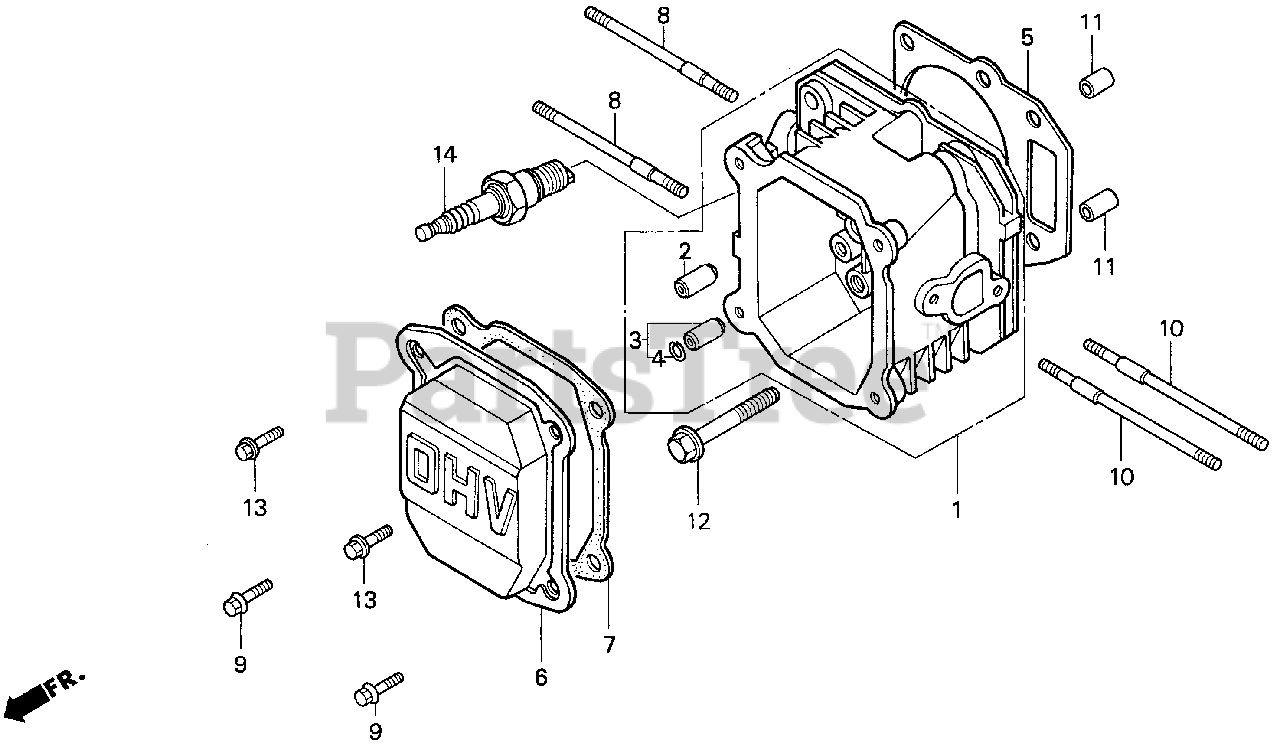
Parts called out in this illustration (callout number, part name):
1	CYLINDER HEAD
2	GUIDE, VALVE (OS)
3	GUIDE, EX. VALVE (OS)
4	CLIP, VALVE GUIDE
5	GASKET, CYLINDER HEAD
6	COVER, HEAD
7	GASKET, HEAD COVER
7	GASKET, CYLINDER HEAD COVER
8	BOLT, STUD (6X83)
9	BOLT, FLANGE (6X13)
10	BOLT, STUD (6X97)
11	PIN, DOWEL (10X16)
12	BOLT, FLANGE (8X50)
13	BOLT, FLANGE (6X14)
14	SPARK PLUG (BP4ES) (NGK)
14	SPARK PLUG (W14EPR-U) (DENSO)
14	SPARK PLUG (BP5ES) (NGK)
14	SPARK PLUG (W16EP-U) (DENSO)
14	SPARK PLUG (BP6ES) (NGK)
14	SPARK PLUG (W20EP-U) (DENSO)
